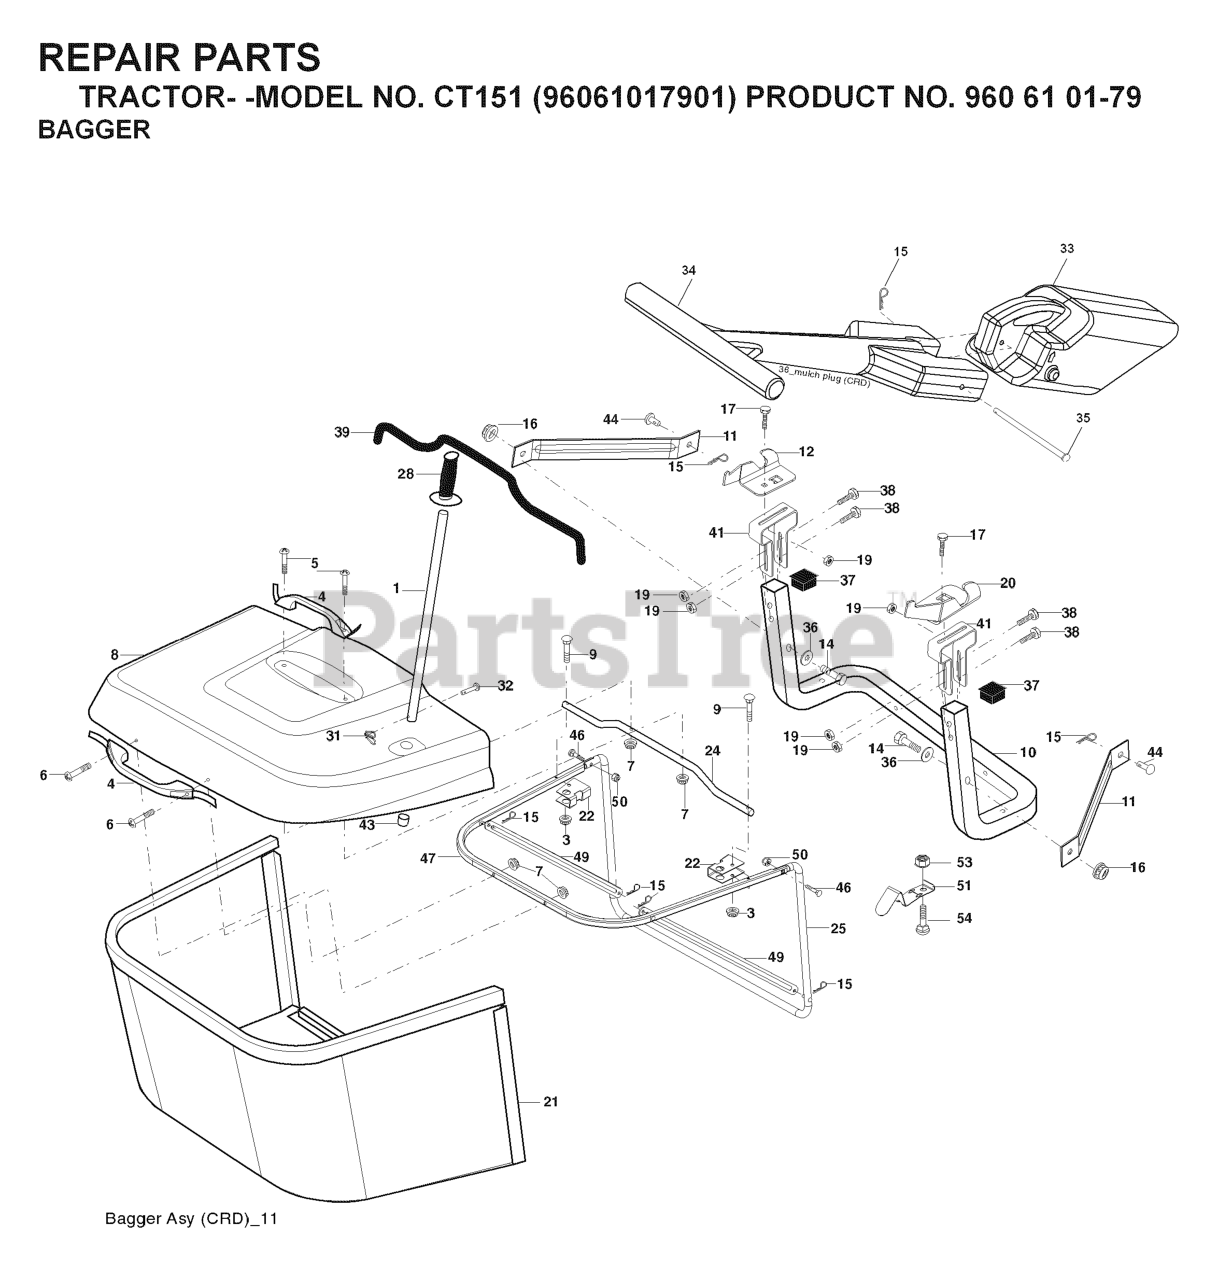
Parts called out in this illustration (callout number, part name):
1	TUBE HANDLE
3	NUT T
4	HANDLE.BAGGER.W/LVRS.BLK.CRD
5	SCREW.PAN.HEAD
6	REPL BY 532 75 00-29
8	COVER.PNT.BGR.CRD.WSLOTS.MS668
9	Bolt Carriage 1/4-20 x 2.25d x Gr.5
10	TUBE
11	BRACKET.SUPPORT.UPPER.BAG.CRD
12	BRKT PIVOT
14	BOLT-HEX EAK
15	RETAINER-SPRNG RB
16	NUT LOCK FLG 3/8-16 UNC
17	RP BOLT 5/16-18 X3/4 ZN/YEL GR
19	NUT LOCK HEX FLANGE 5/16-18
20	BRKT.PIVOT.RH.CRD
21	BAGGER.ASM.CRD.2007
22	BRKT.SIDE.BAG.CRD
24	TUBE.PIVOT.BAG.CRD.BLACK
25	PIPE
28	GRIP.HANDLE.BLACK
31	RETAINER CLIP
32	RIVET,DRILLED
33	PLUG.MULCHER.92 CRD
34	HANDLE.MULCHER.92.CRD (2 2)
36	WASHER
37	Plug Support Bagger CRD
38	BOLT.5/16-18X2.5
39	SEAL.TRIM.37'
41	BRKT.VERT.ADJ.BAGGER.CRD
43	PLUG, TUBING END
46	BOLT.CARRIAGE.5/16-18
47	PIPE
49	ROD
50	NUT.71038.31-18.HEX.NYLOCK
51	LATCH
53	NUT
54	BOLT
